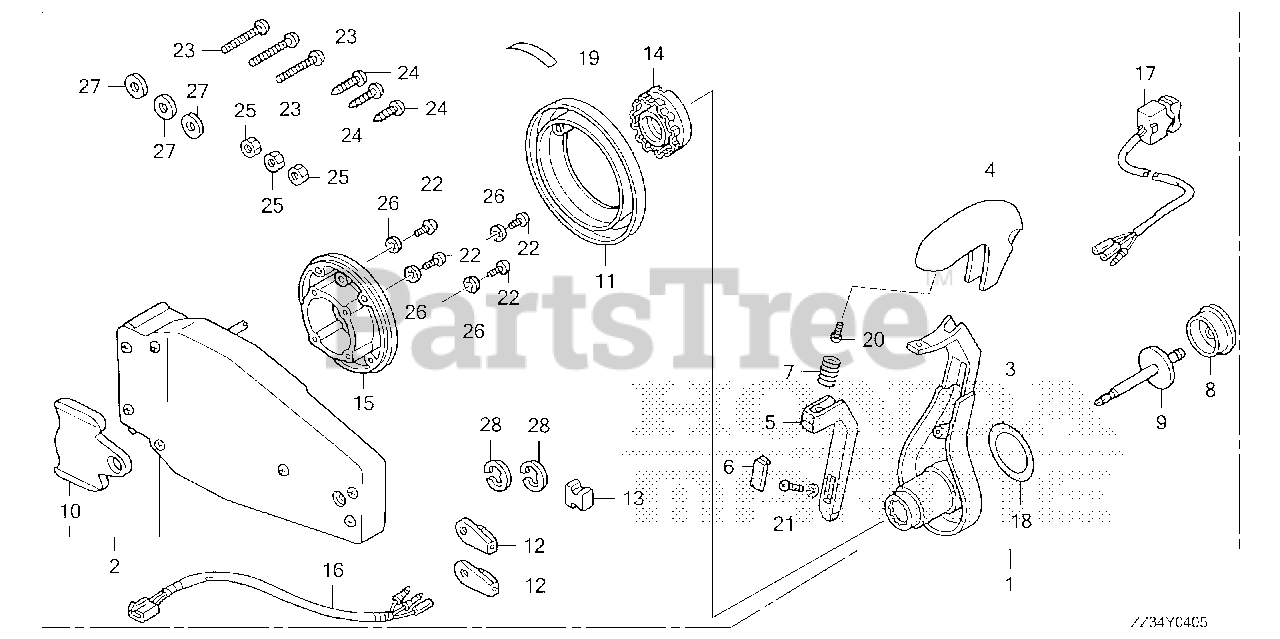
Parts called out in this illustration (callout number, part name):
1	BOX KIT, REMOTE CONTROL (FLUSH MOUNT)(L)
2	HOUSING ASSY., L. (INNER) (FLUSH MOUNT)
3	HANDLE, REMOTE CONTROL
4	COVER, GRIP
5	ARM, NEUTRAL LOCK
6	COVER, LOCK ARM
7	SPRING, NEUTRAL LOCK ARM
8	BUTTON, THROTTLE
9	SHAFT, THROTTLE BUTTON
10	PLATE, DWELL
11	COVER ASSY.
12	TERMINAL, CABLE
13	SPACER, CABLE CLAMP
14	HOLDER, NEUTRAL LOCK
15	BASE
16	SUB-HARNESS ASSY., POWER TRIM-TILT (C)
17	SWITCH ASSY., POWER TRIM-TILT (C)
18	MARK, HANDLE FLUSH MOUNT
19	MARK, FLUSH MOUNT
20	SCREW, PAN (5X16)
21	SCREW, TRUSS (4X12)
22	SCREW, PAN (5X30)
23	SCREW, PAN (6X35)
24	SCREW, TAPPING (6X30)
25	NUT, HEX. (6MM)
26	WASHER, LOCK (5MM)
27	WASHER, PLAIN (6MM)
28	E-RING (6MM)
